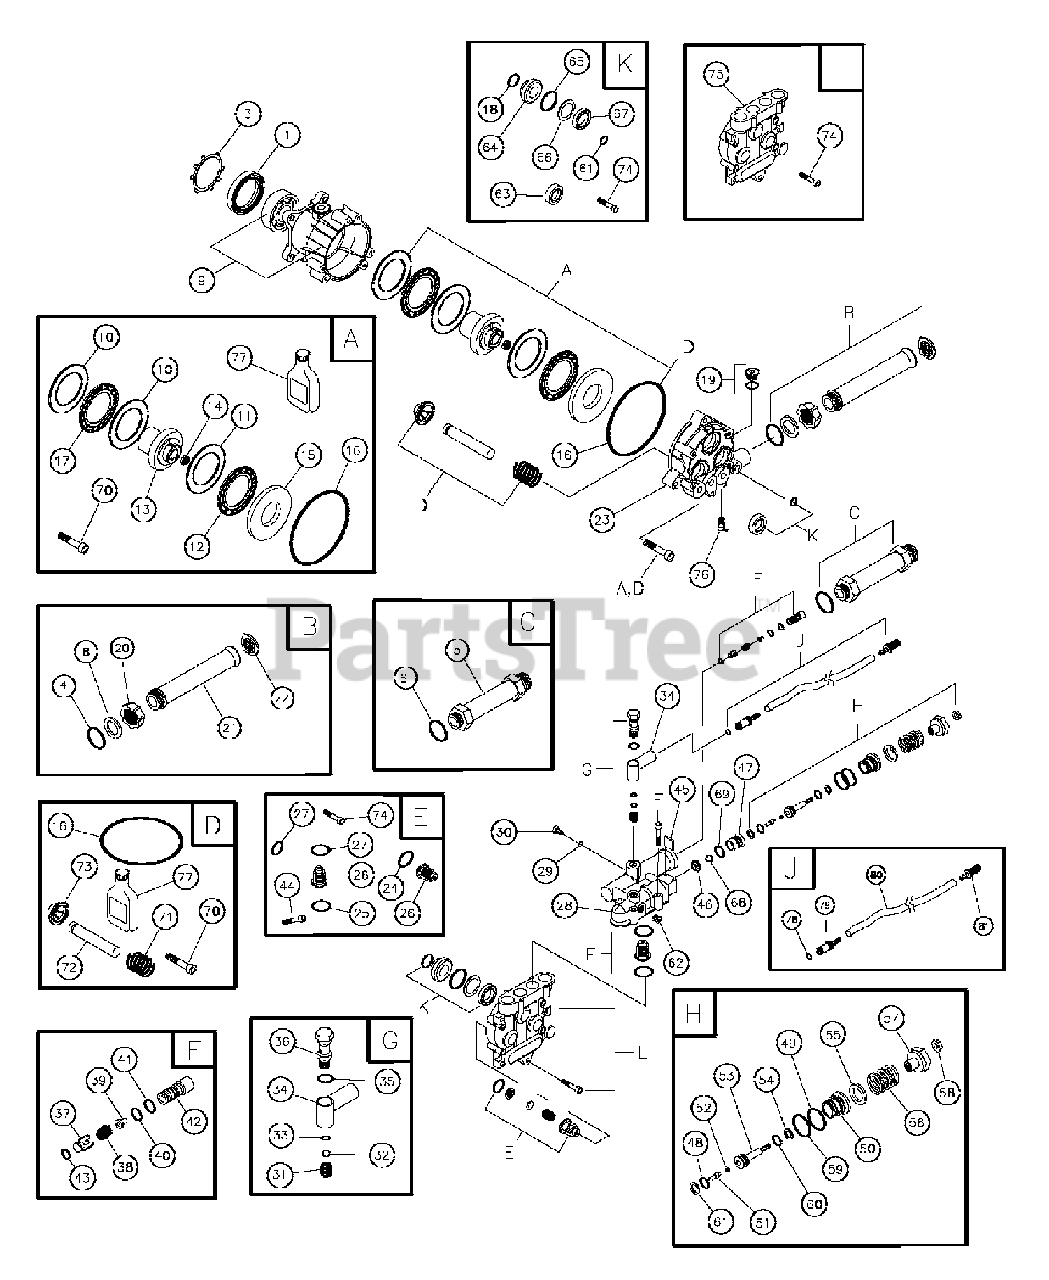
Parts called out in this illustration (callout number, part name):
1	SEAL, 40 x 52 x 7
3	RETAINER RING
9	ENGINE ADAPTER & BEARING
14	CAP
16	O-RING, 80.60 x 2.62
19	CAP, Oil
20	GARDEN HOSE w/FINGER GRIP
21	EXTENSION, INLET
23	PISTON HOUSING
26	ASSY, Check Valve
28	MANIFOLD
29	O-RING, 4x2
30	SCREW, Venturi
34	CONNECTION, Chemical Inlet
36	FIXING SCREW
37	VALVE, Non-Return
39	INJECTION NOZZLE, M6 Flat
42	INJECTION NIPPLE
46	VALVE, Seat Plate Brass
47	VALVE, Seat Stainless
50	VALVE, By Pass, Brass
51	PISTON
52	SPRING, Easy Start
53	PISTON, Body
55	SPACER
56	SPRING, Regulation Press
57	NUT, Regulation Press
58	NUT
62	CAP, 1/8
64	SEAL
67	SEAL, H.P.
68	BALL, 7mm Stainless Steel
69	O-RING, 9.25 x 1.78
71	SPRING
72	PISTON, 14 x 63, Stainless Steel
73	SPRING PLATE
75	HEAD, Pump
76	THERMAL RELIEF
77	OIL BOTTLE
79	TUBE, Inlet Support
80	TUBE, Chemical
81	FILTER
A	KIT, WOBBLE PLATE BEARING
B	KIT, WATER INLET, ANODIZED
C	KIT, OUTLET, ANODIZED
D	KIT, PISTON
E	KIT, CHECK VALVES
F	KIT, INLET CHECK
G	KIT, CHEMICAL INJECTION
H	KIT, UNLOADER
J	KIT, CHEMICAL HOSE
K	KIT, SEAL SET
L	KIT, HEAD BRASS
